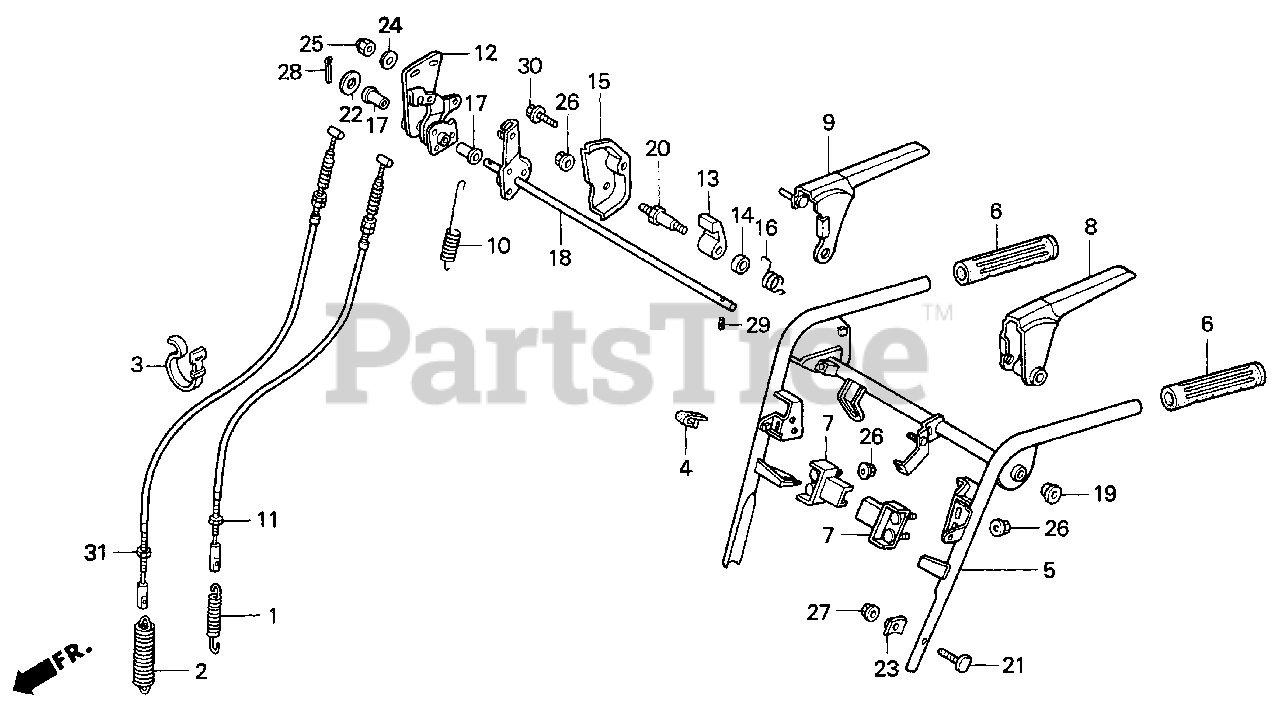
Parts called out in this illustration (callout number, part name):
1	SPRING, TENSIONER ROLLER
2	SPRING, TENSIONER ROLLER (AUGER)
3	BAND, WIRE (95MM)
5	PIPE, HANDLE (UPPER)
6	GRIP, HANDLE
7	STOPPER, CHANGE LEVER
8	LEVER, CLUTCH
9	LEVER, AUGER CLUTCH
10	SPRING, CLUTCH LEVER
11	CABLE, CLUTCH
12	BOSS, CAM LOCK
13	RATCHET, LEVER
14	COLLAR, RATCHET
15	COVER, RATCHET
16	SPRING, RATCHET
17	BUSH (13X22.5) (GRAY)
18	SHAFT, CLUTCH LEVER
19	BUSH (14MM)
20	BOLT, PIVOT (6MM)
21	BOLT, HANDLE HOLDER (8X41)
21	BOLT, HANDLE HOLDER
22	WASHER, THRUST (10MM)
23	WASHER, FRAME JOINT
24	WASHER (6MM)
25	NUT, CAP (6MM)
26	NUT, FLANGE (6MM)
27	NUT, FLANGE (8MM)
28	PIN, SPLIT (3.0X18)
29	PIN, SPRING (4X16)
30	BOLT, FLANGE (6X10)
31	CABLE, CLUTCH
